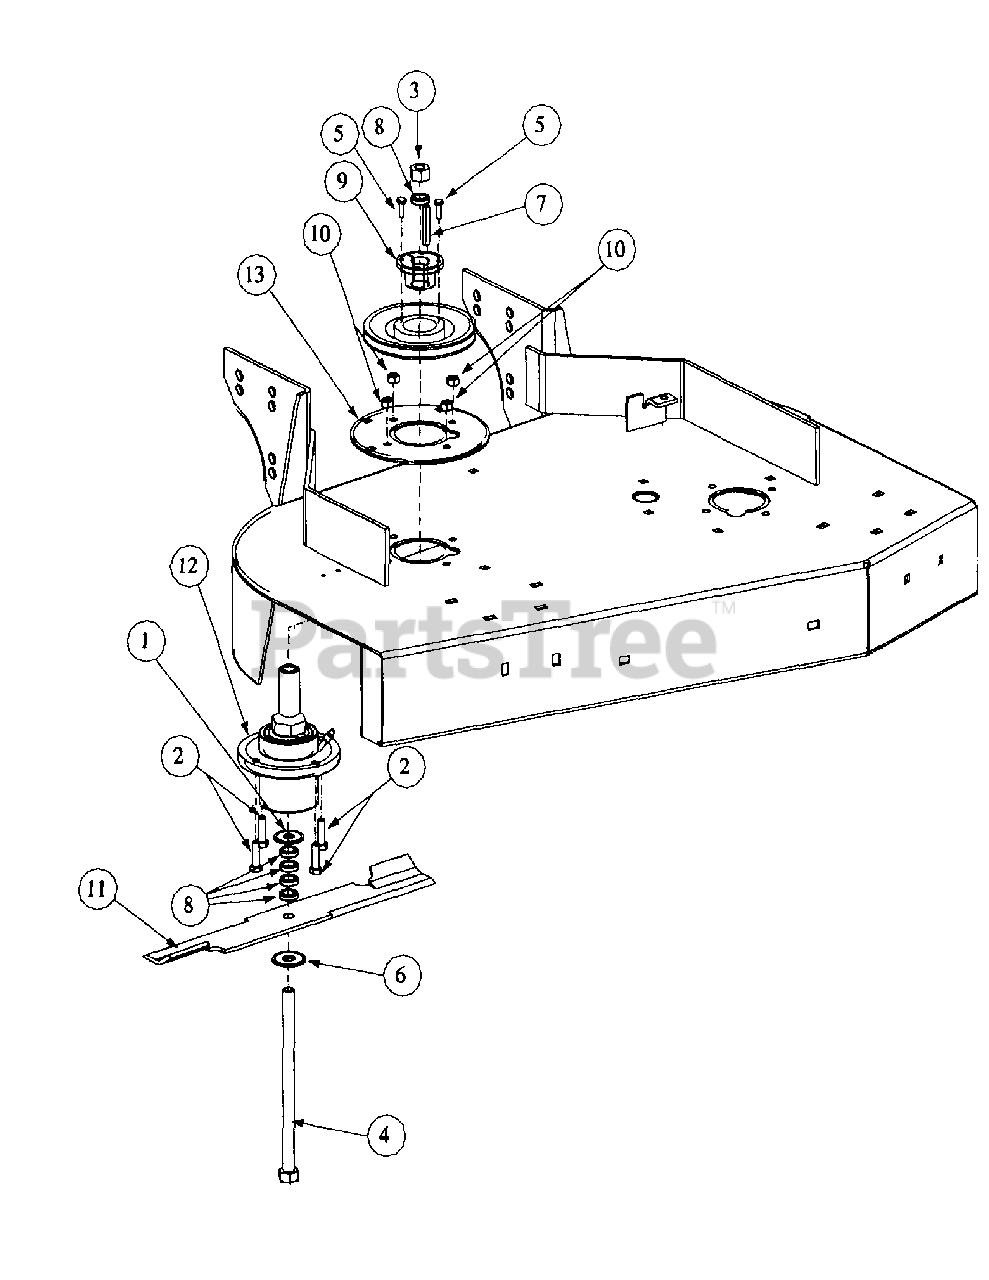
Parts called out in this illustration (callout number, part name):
1	Flat Washer, 1-1/2 x 5/8 x .05
2	Hex Cap Screw, 3/8-16 x 1-1/4
3	Hex Nut, 5/8-11
4	Hex Cap Screw, 5/8-11 x 9-1/2
5	Hex Cap Screw, 1/4-20, .75
6	Flat Washer, 5/8 Zinc
7	Key Stick, 1/4 x 1/4 x 2
8	Blade Spacer, 5/8 ID, 1/4 Thick
9	Bushing
10	Lock Nut, 3/8-16
11	Blade 18"
12	Spindle Assembly
13	Plate, Spindle Backing
